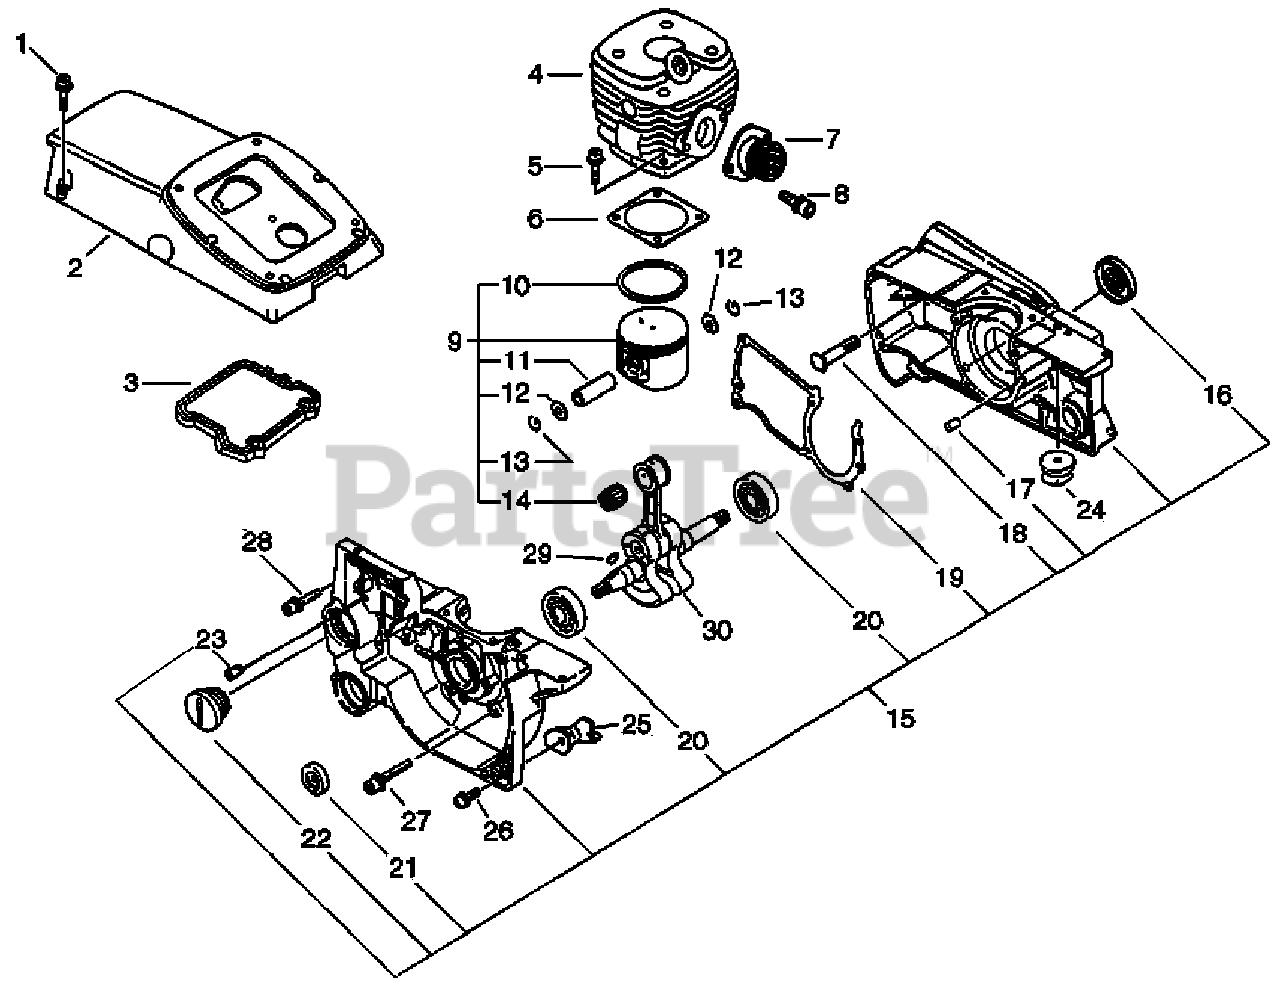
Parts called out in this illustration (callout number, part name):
1	BOLT 5×20
2	COVER, ENGINE
3	CUSHION
4	CYLINDER
5	BOLT 5×25
6	GASKET, CYLINDER
7	BELLOWS, INTAKE
8	BOLT 5×14
9	PISTON KIT
10	RING, PISTON
11	PIN, PISTON 12
12	WASHER, THRUST
13	RING, SNAP
14	BEARING, NEEDLE
15	CRANKCASE KIT
16	SEAL, OIL
17	PIN, LOCATING 5×10
18	STUD, GUIDE BAR
19	GASKET, CRANKCASE
20	BEARING, BALL 6202
21	SEAL, OIL
22	CAP, OIL TANK
23	VENT ASSY
26	SCREW 5×14
27	BOLT M5×35
28	BOLT 5×20
29	KEY, WOODRUFF
30	CRANKSHAFT ASSY
